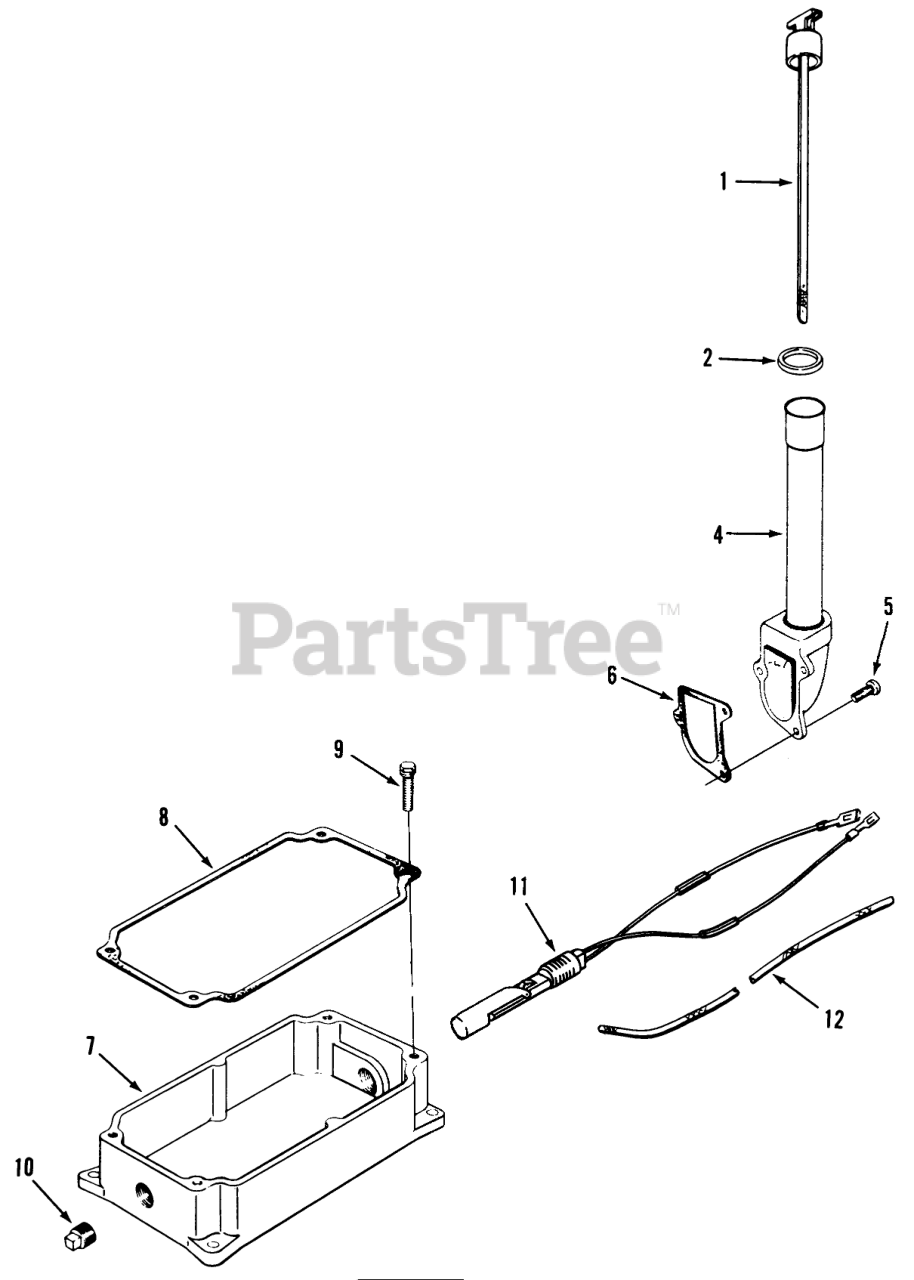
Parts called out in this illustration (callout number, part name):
1	Dipstick
2	0-Ring
4	Adapter-Oil Fill
5	Screw
6	Gasket
7	Oil Pan
8	Gasket
9	Screw
11	Float Switch Kit (Includes Items 12 & Decal) 310S Float Switch Kit (Includes Items 12 & Decal) 312S
12	Sleeve
